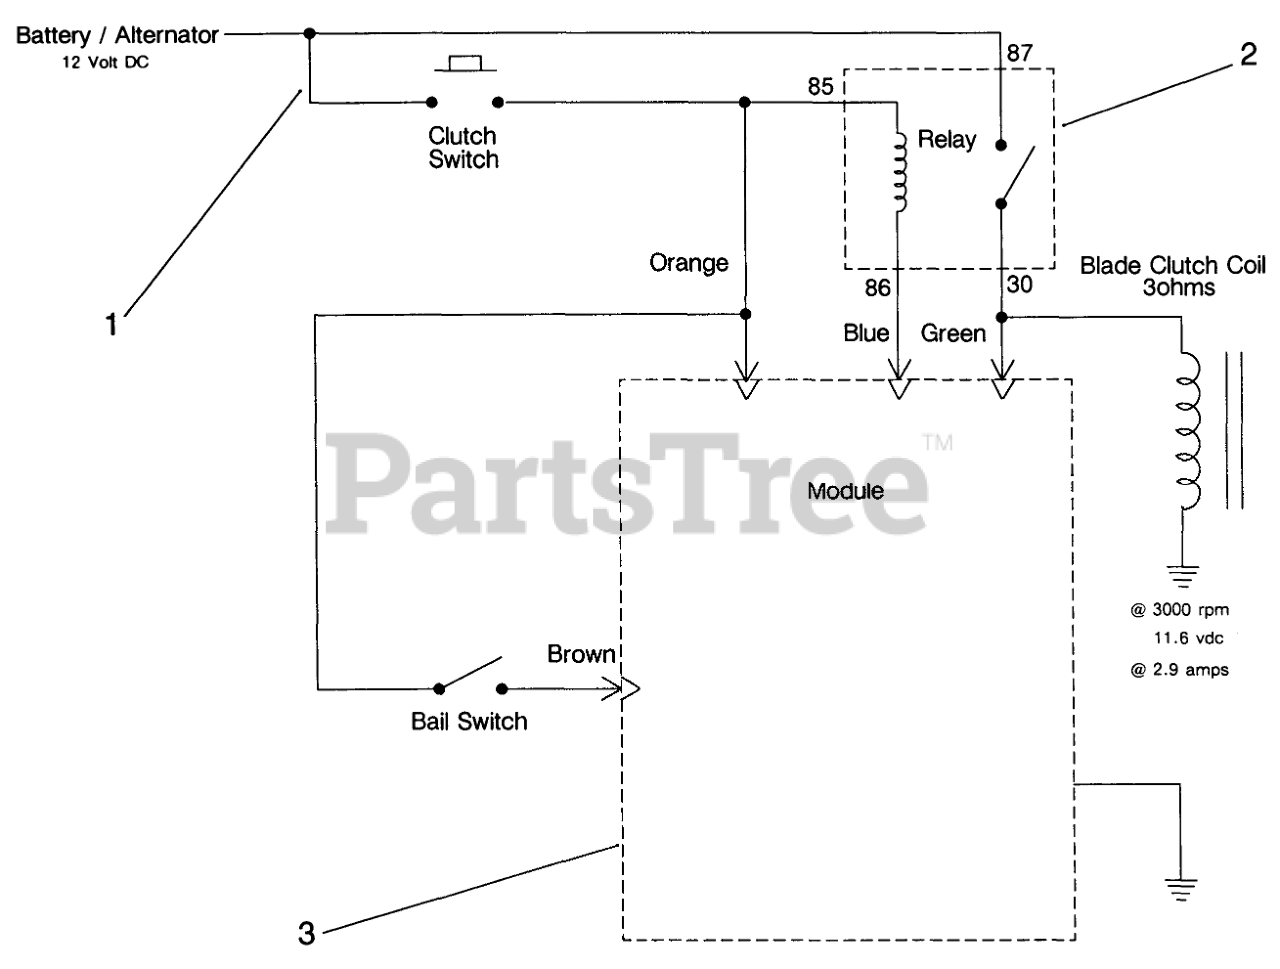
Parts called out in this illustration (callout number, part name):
1	Wire HARness
2	Module
3	Relay
